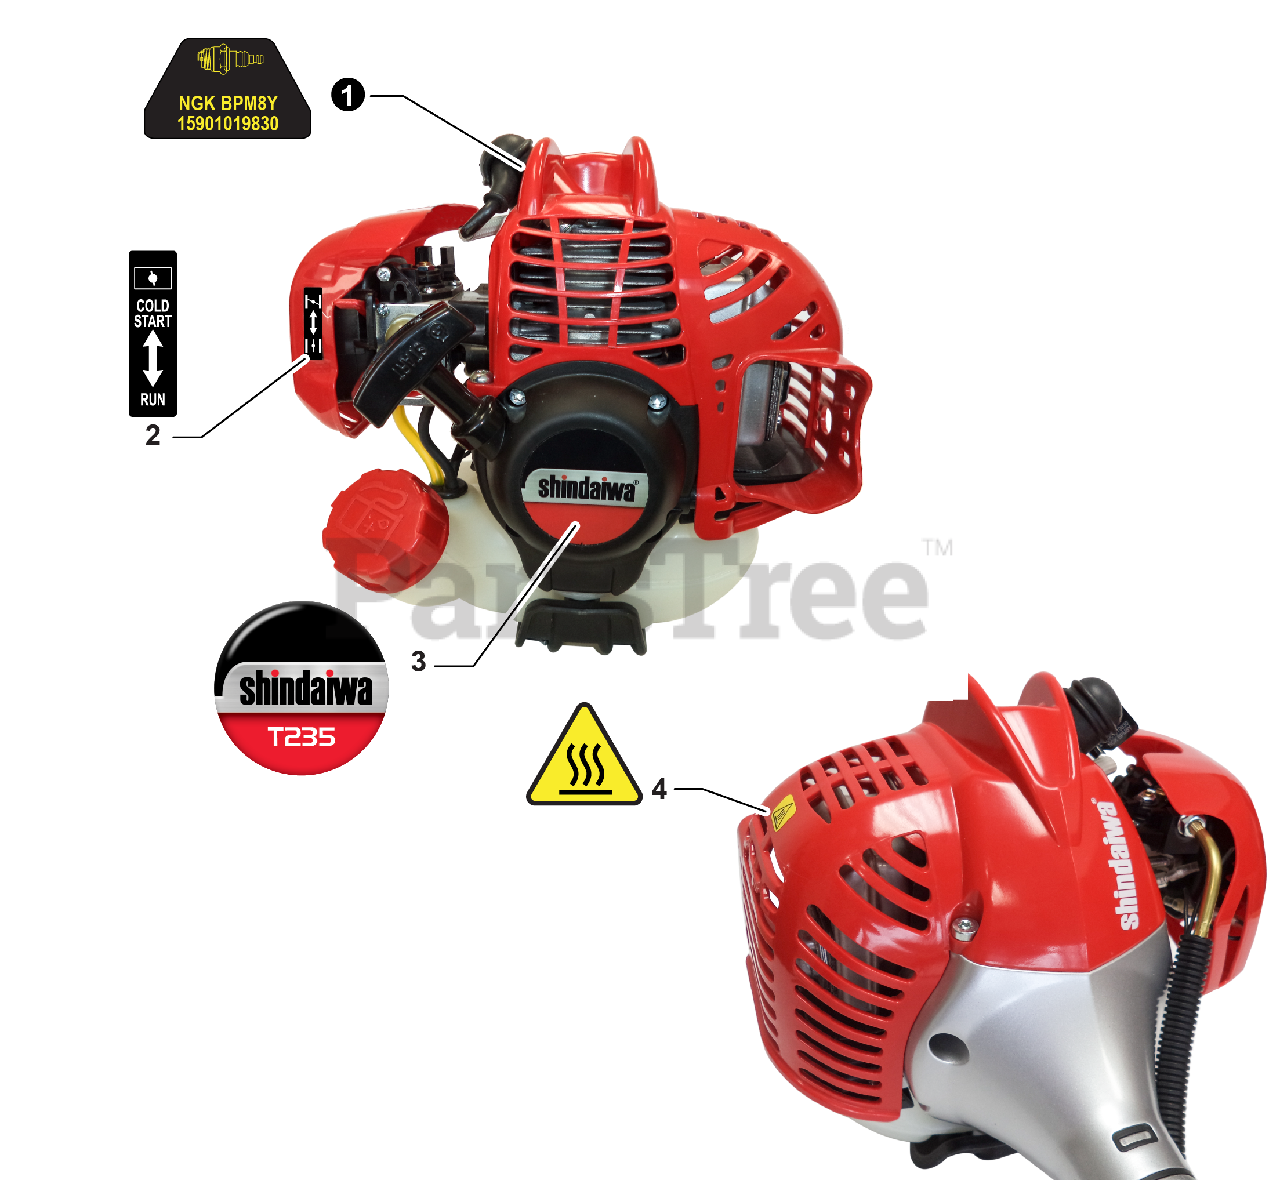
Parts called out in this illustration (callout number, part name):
1	LABEL, SPARK PLUG - BPM8Y
2	LABEL, CHOKE
3	LABEL, SHINDAIWA - T235
4	LABEL, CAUTION - HOT
